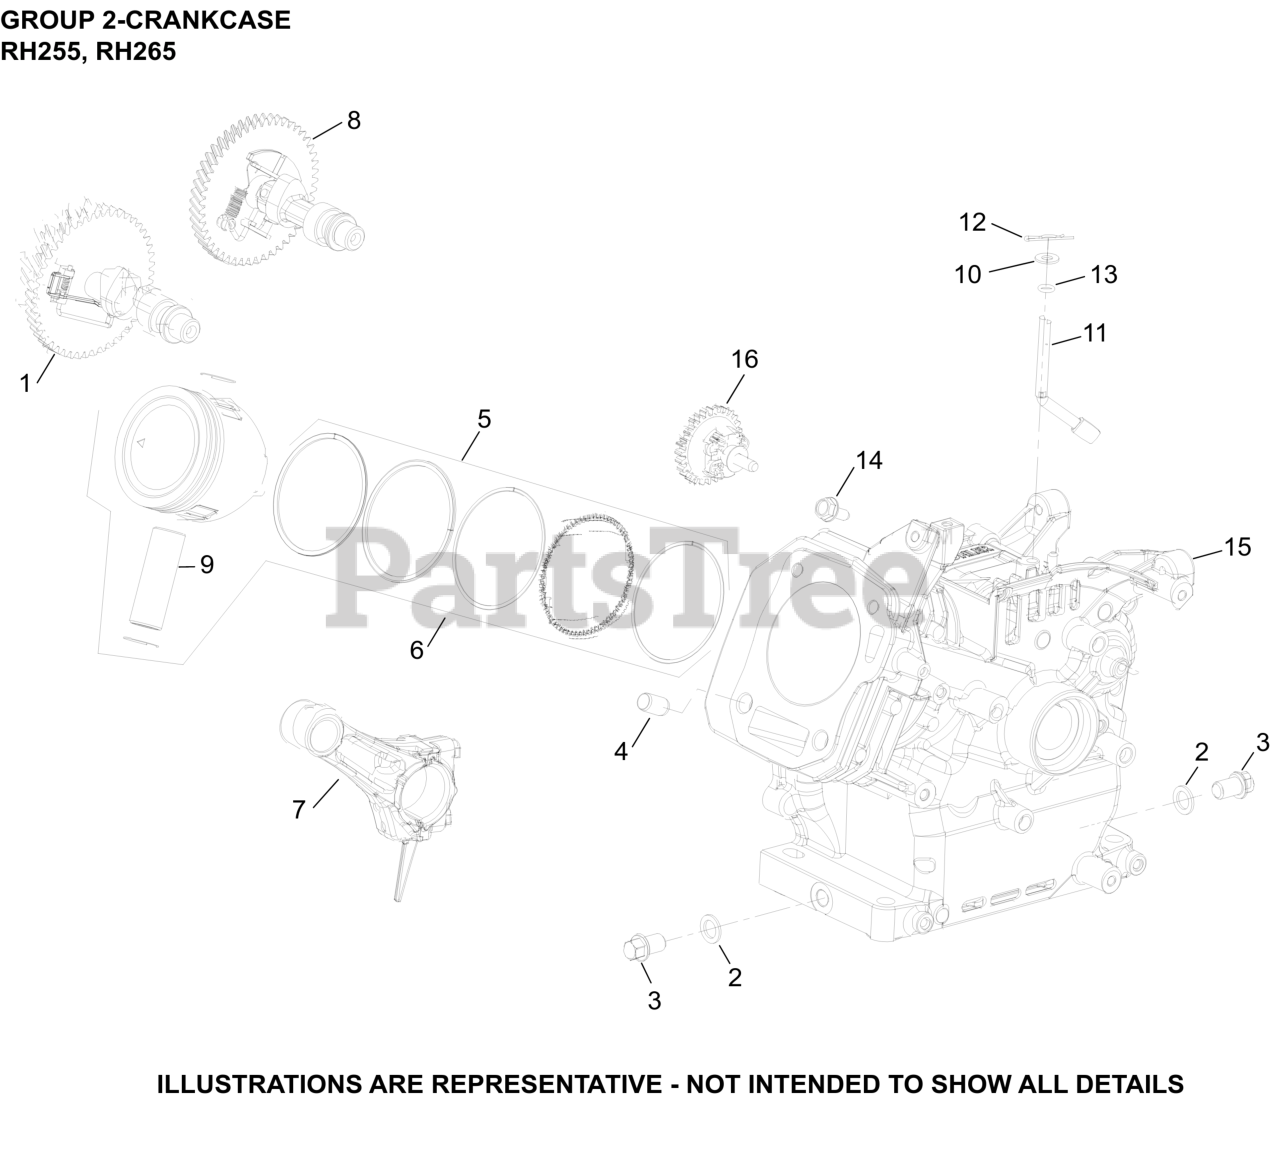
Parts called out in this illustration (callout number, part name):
1	CAMSHAFT, ASSEMBLY
2	WASHER, DRAIN PLUG
3	KIT, DRAIN PLUG
6	KIT, PISTON (STD)
7	ROD, CONNECTING ASSEMBLY
9	PIN, PISTON
10	WASHER, FLAT (DIA 13mm O.D.)
11	CROSS SHAFT
12	CLIP, GOVERNOR SHAFT
16	GOVERNOR ASSEMBLY
